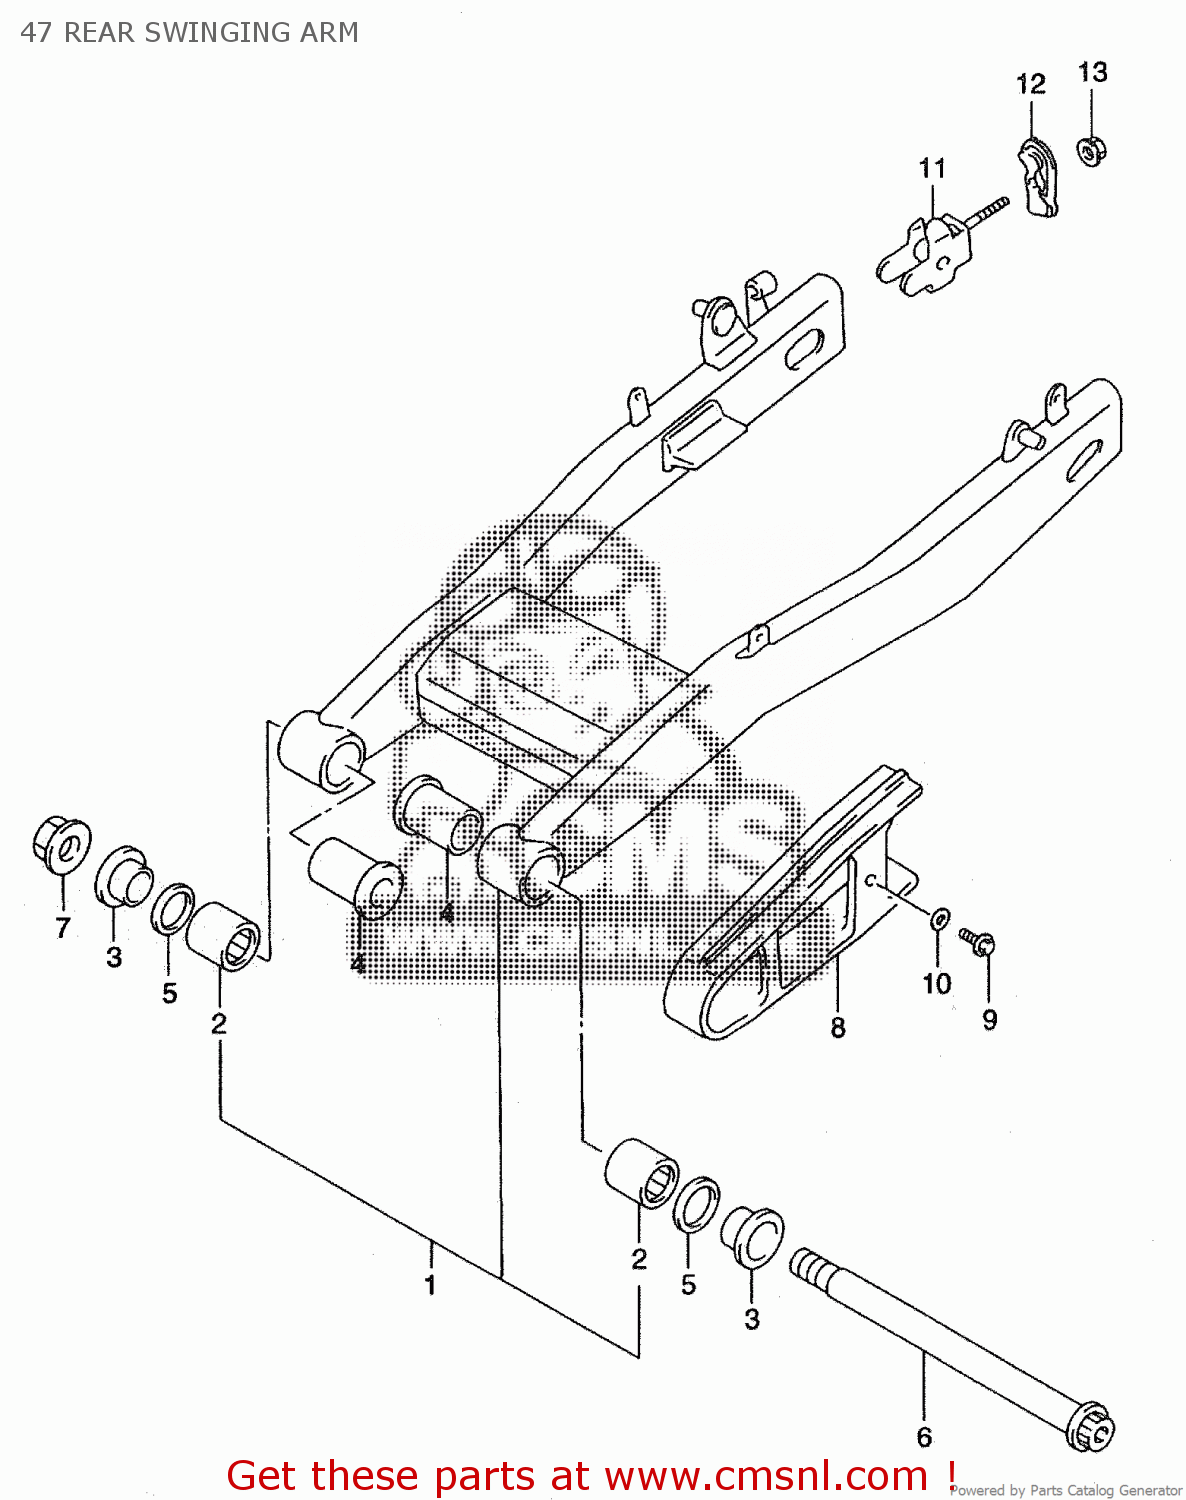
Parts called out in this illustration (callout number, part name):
2	BEARING(25X33X35)
5	SEAL,OIL(25X35X5)
7	NUT ,18MM
9	BOLT(6X20)
10	SPACER(6.5X9X3.8)
11	ADJUSTER,CHAIN
12	PLATE,CHAIN ADJUSTER
13	NUT
